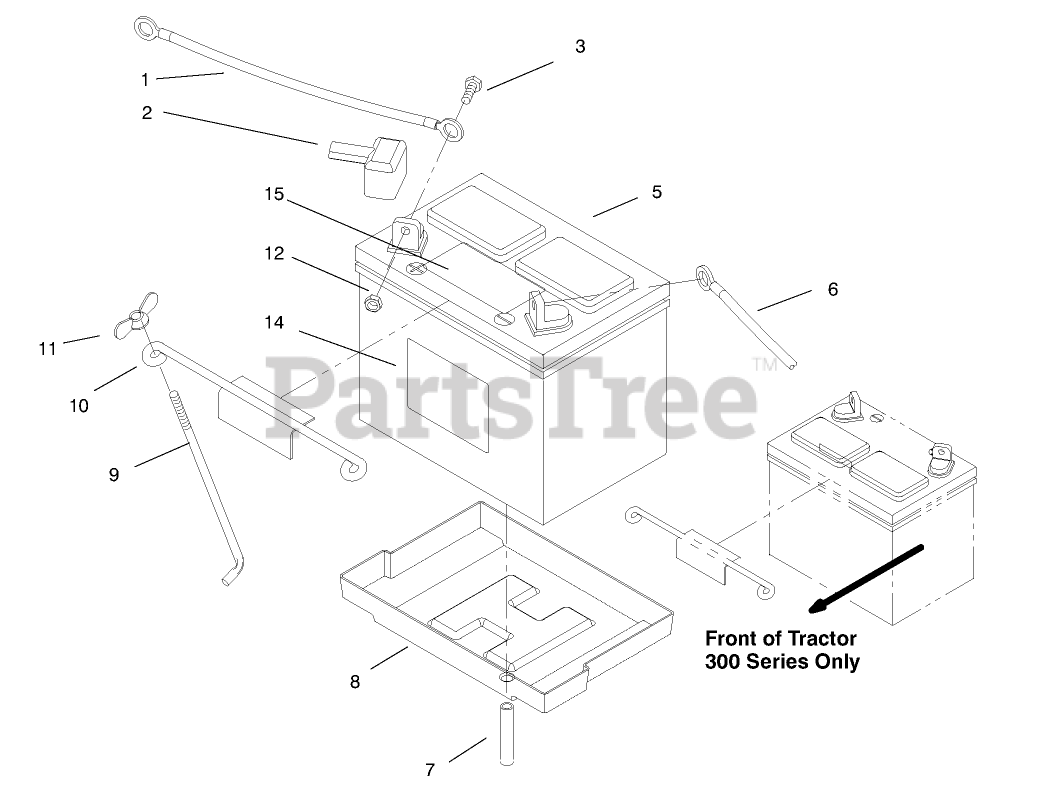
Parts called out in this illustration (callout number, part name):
1	CABLE-BLACK
2	BOOT-TERMINAL
3	SCREW-HH
7	TUBE-21" BATTERY DRAIN
8	TRAY-BATTERY
9	HOOK-BATTERY RETAIN
10	HOLDDOWN-BATTERY
11	NUT-WING
12	NUT-LOCK, NI
